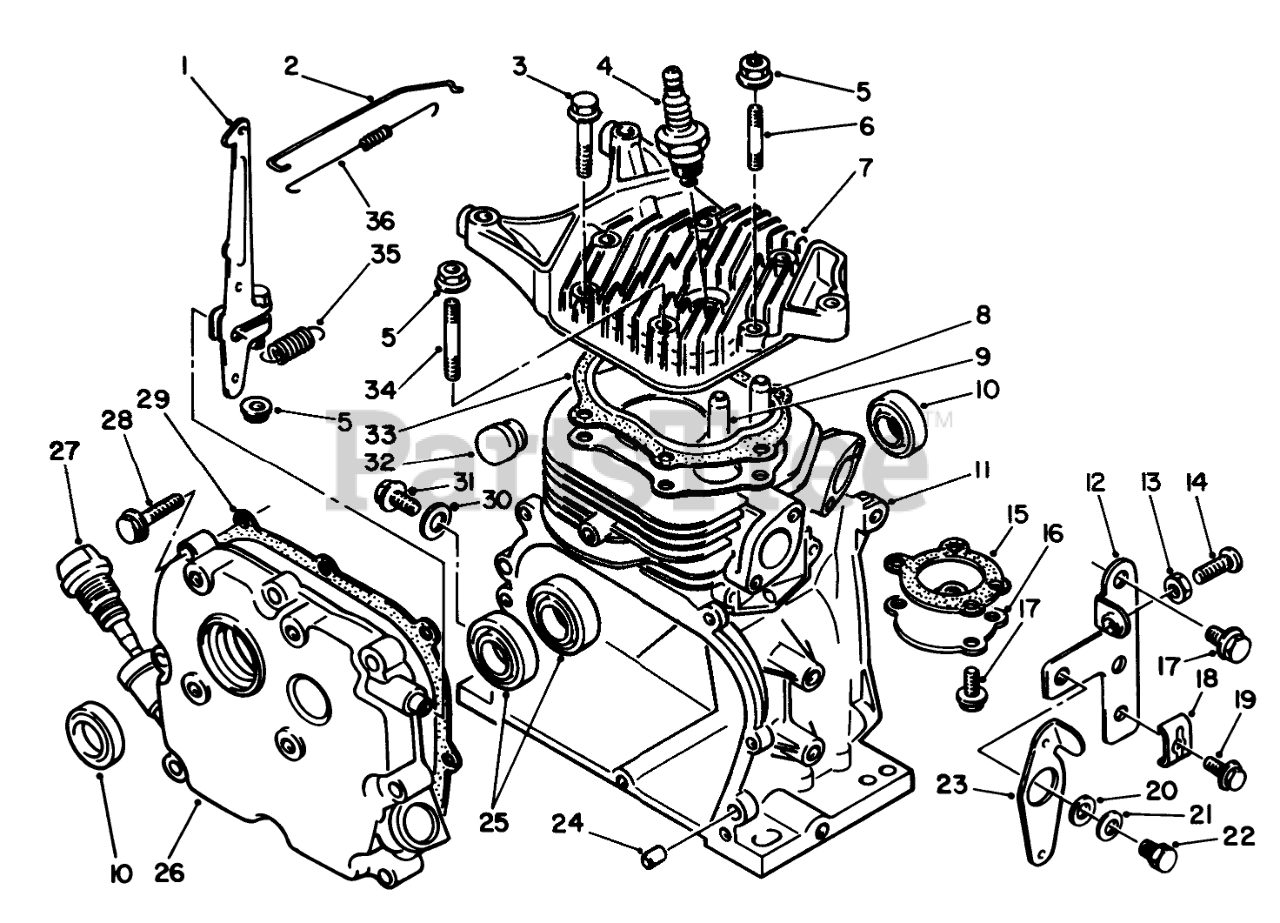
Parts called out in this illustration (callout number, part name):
1	Lever-Throttle Conlrol
2	Rod-Carburetor
4	Spark Plug
6	Bolt-Stud
7	Cylinder Head
8	Guide-Intake Valve
9	Guide-Exhaust Valve
10	OIL SEAL
11	Cylinder Assembly
12	Bracket-Governor Control
13	Nut-Jam
14	Screw-Round Phillips Hd.
15	GASKET
16	Cover-Level Sensor
18	CLAMP-CABLE
20	WASHER-THROTTLE
21	Washer
23	Lever
25	Bearing
26	Cover-Crankcase Side
27	Gauge-Oil Level
29	CRANKCASE GASKET
30	Gasket
31	Bolt
33	CYL. GASKET
34	Bolt-Stud
35	SPRING
36	SPRING
